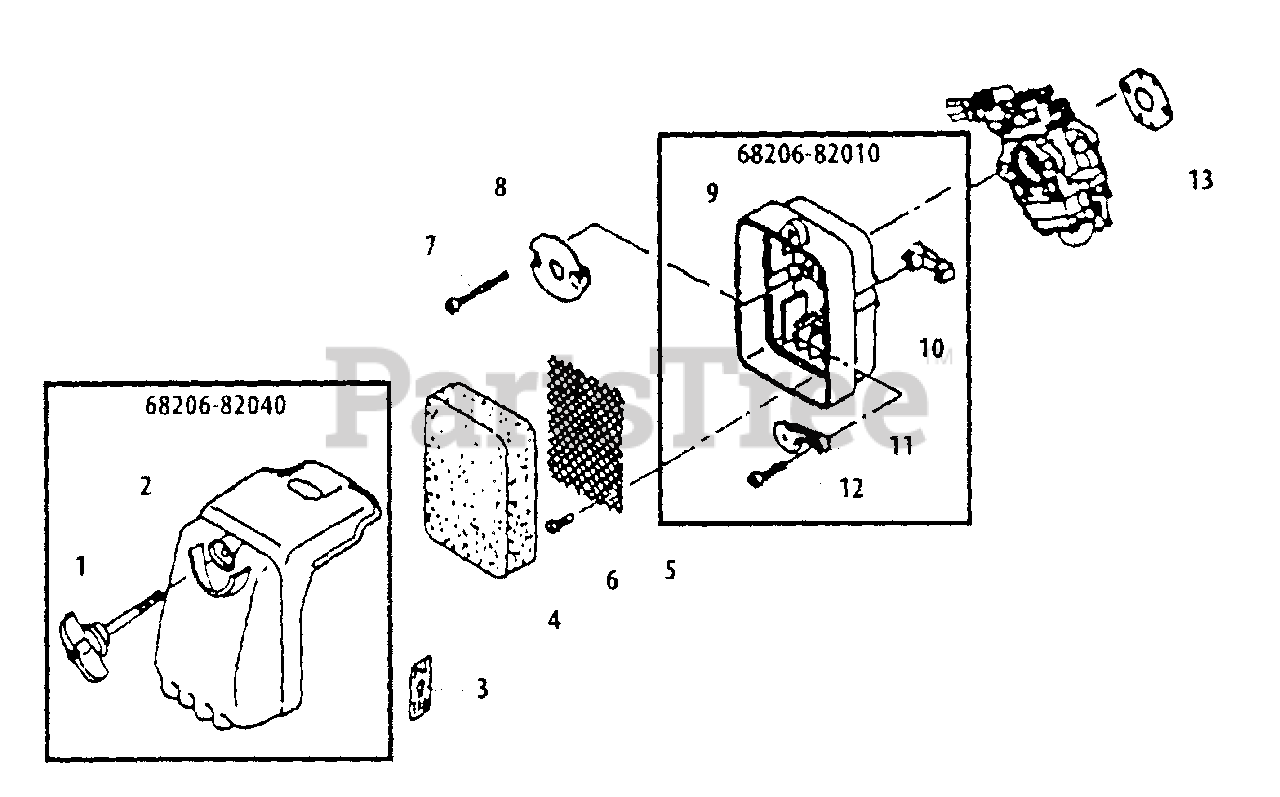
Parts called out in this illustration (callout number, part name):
1	COVER ASSY, AIR FILTER
2	COVER, AIR FILTER
3	LABEL, CHOKE
4	FILTER, AIR
5	SCREEN, FILTER
8	PLATE, PREVENT
9	CASE, AIR FILTER
10	LEVER, CHOKE
11	PLATE, SHUTTER
13	GASKET, INTAKE
68206-82010	CASE ASSY, AIR FILTER
68206-82040	COVER ASSY, AIR FILTER
